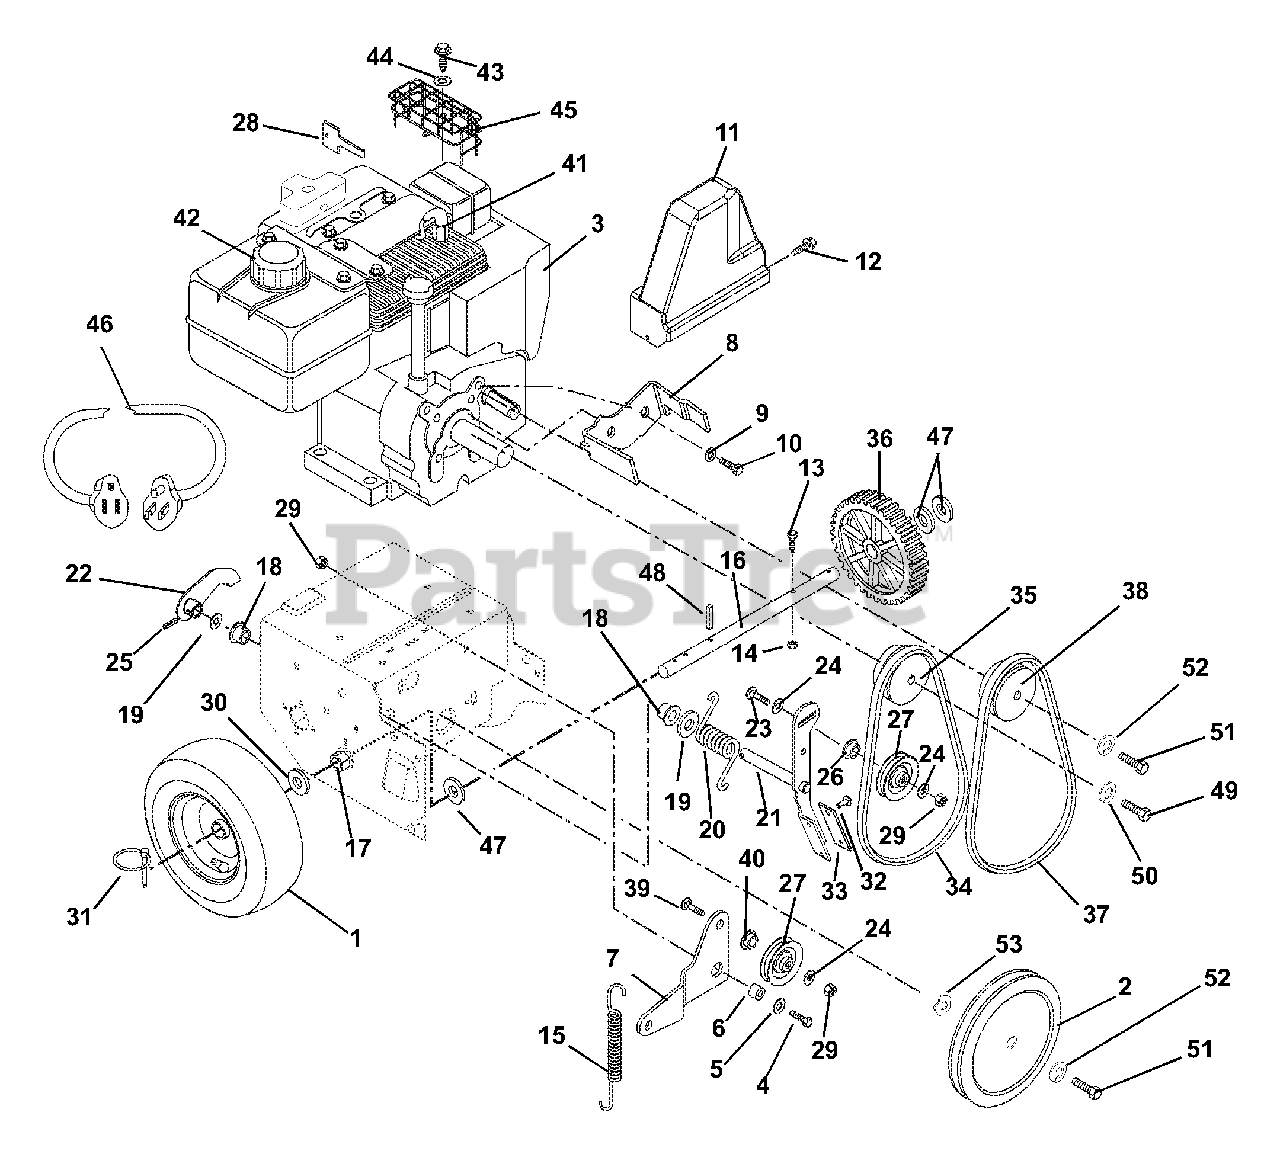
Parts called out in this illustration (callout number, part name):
1	WHEEL, 4.1-6
1	TIRE
1	WHEEL/TIRE ASSEMBLY 4.1-6X12.8
2	PULLEY, 3L W/HUB, .625 X 8.0
3	ENGINE, 5HP TEC LH195SA RECOIL
3	ENGINE, 5.5HP TEC LH195SP 120V
3	ENGINE, 6HP TEC OH195SA RECOIL
3	ENGINE, 6HP TEC OH195SA 120V
3	ENGINE, 7HP TEC OH195SA RECOIL
3	ENGINE, 7HP TEC OH195SA 120V
4	@BLT-HEX .31-18X.75 GR5 YWZC
5	@WSHR-FL-STL.38X.875X.083 YWZC
6	SPACER BUSHING .5 X .32 X .163
7	IDLER ARM
8	FINGER, BELT
9	WSHR-LK .312X.097 HVY YWZC
10	BLT-HEX .31-24X.75 YWZC GR5
11	COVER, BELT
12	@SCR-TAP .25-20X.37 HWH YWZ TR
13	BLT-HEX .25-20X1.75 GR8 YWZC
14	@NUT-LK-CTR .25-20 YWZC
15	SG-TENS .047X.44X3.37 WLD 1.47
16	AXLE SHAFT, COMPACT W/PIN LOCK
17	BSHG-FLG .750X.873HEXX.53X1.18
18	BSHG-FLG .500X.625X.500X.750
19	WSHR-FL-STL .520X.810X.033YWZC
20	SG-TORS .148X1.0X1.53
21	CLUTCH ARM W/BRAKE PAD
22	ARM-CLUTCH
23	@BLT-RDHDSQNK .31-18X1.25 G5YZ
24	@WSHR-FL-STL.38X.875X.083 YWZC
25	PIN-ROLL .156X.88
26	SPCR, BRG .315X.50X.688X.281
27	IDLER
28	KEY, PUSH/PULL - TECUMSEH
29	@NUT-LK-CTR .31-18 YWZC
30	WSHR-FL-STL.754X1.125X.062YWZC
31	PIN-LOK .31X1.75
32	RVT-TBLR .187X.437 RH ST PL
33	BRAKE LINING
34	BELT,4L TO BE REPLACED07200021
34	V-BELT, 4L-RAW EDGE
35	SHEAVE, ENGINE
35	SHEAVE, ENGINE OH195SA
37	V-BELT, 3L-COGGED
38	SHEAVE, CAMSHAFT OH/LH195SA
39	BLT-RDHDSQNK .31-18X1.0 SHTYZ
40	BSHG, FLG .325X.499X.26X.88
41	PLUG, SPARK
42	CAP, FUEL - TECUMSEH
43	SCR-TAP 10-16X.75 YWZC
44	@WSHR-FL-STL.219X.50X.049 YWZC
45	MUFFLER GUARD 5 HP
46	CORD, ELECTRIC START CORD 120V
47	WSHR-FL-STL .755X1.25X.125 YZ
48	PIN-ROLL .188X1.25
49	BLT-HEX .38-24X1.0 GR5 YZ EP80
50	@WSHR-LK .38X.094 REG YWZC
51	BLT-HEX .25-28X.75 GR5 YZ EP80
52	WSHR-LK .250X.077 HVY YWZC
53	WSHR-WAVE .69X.84X.011
